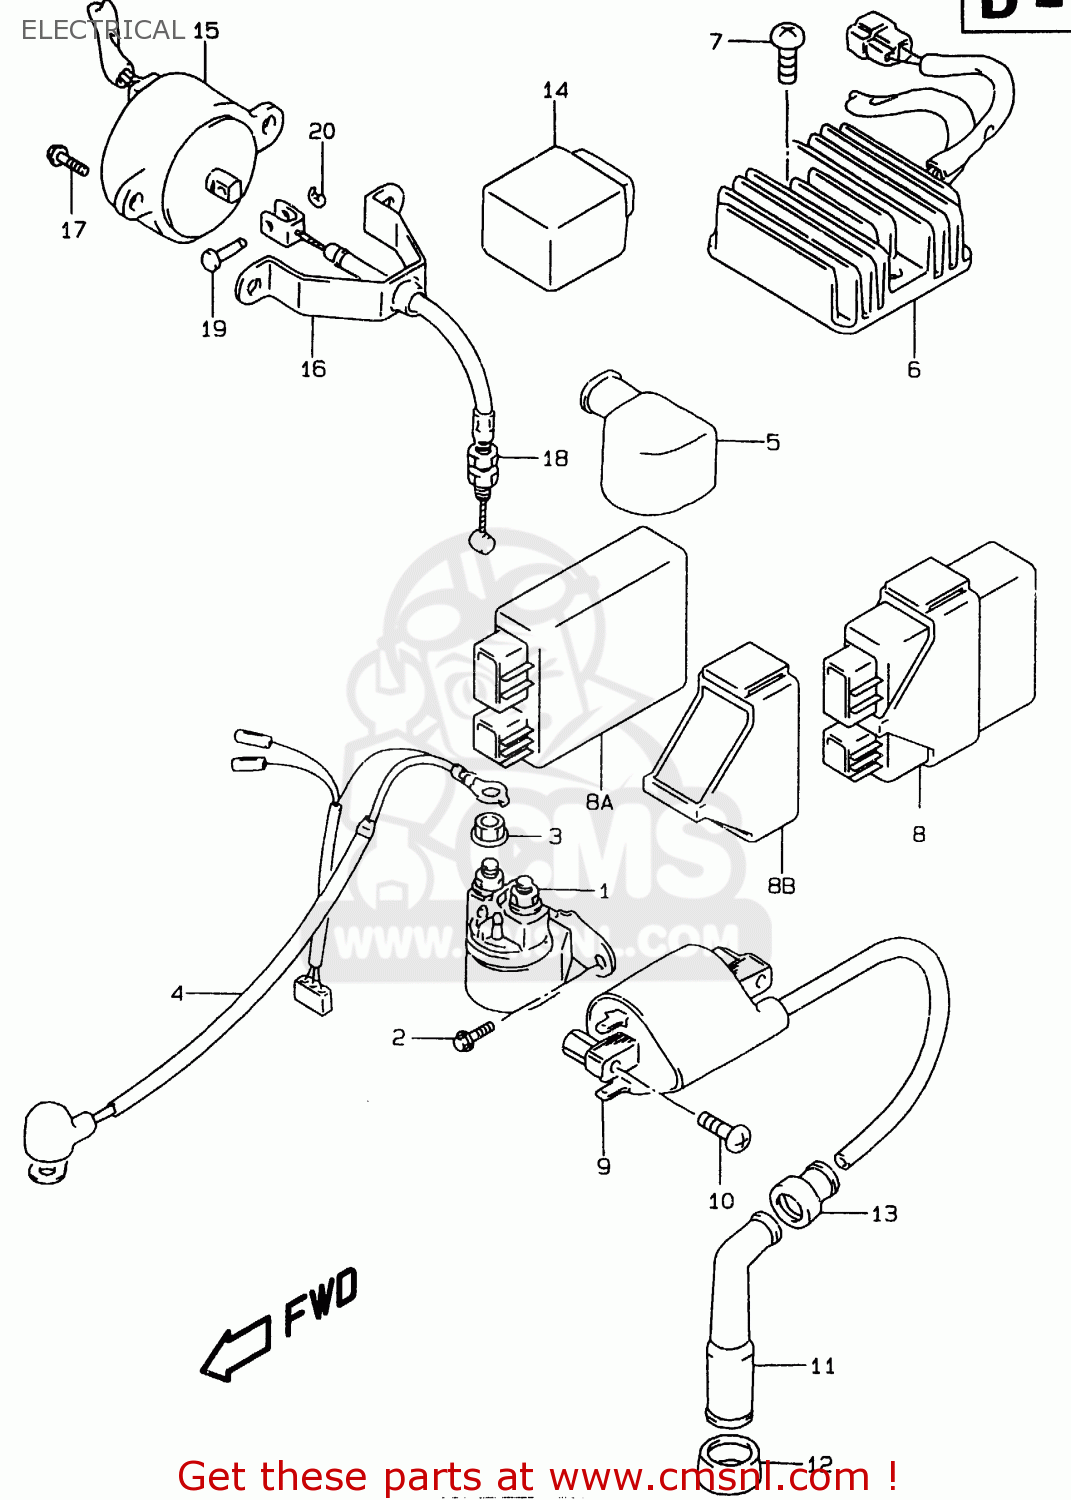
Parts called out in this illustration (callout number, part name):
1	RELAY ASSY,STARTING MOTOR
2	BOLT
3	NUT
4	WIRE,STARTER MOTOR
5	CAP,STARTER RELAY TERMINAL
6	RECTIFIER ASSEMBLY
7	SCREW
8	IGNITER ASSY
8A	IGNITOR ASSY
8B	CUSHION,IGNITOR
9	COIL ASSY,IGNITION
10	SCREW 5X12
11	CAP ASSY,SPARK PLUG
12	SEAL,SPARK PLUG CAP
13	SEAL,HIGH TENSION CORD
14	CONTROL UNIT,DECOMP
15	SOLENOID ASSY,DECOMP
16	BRACKET,DECOMP SOLENOID
17	BOLT
18	CABLE ASSEMBLY,DECOMPRESSION
19	PIN(4X12.5)
20	E RING
